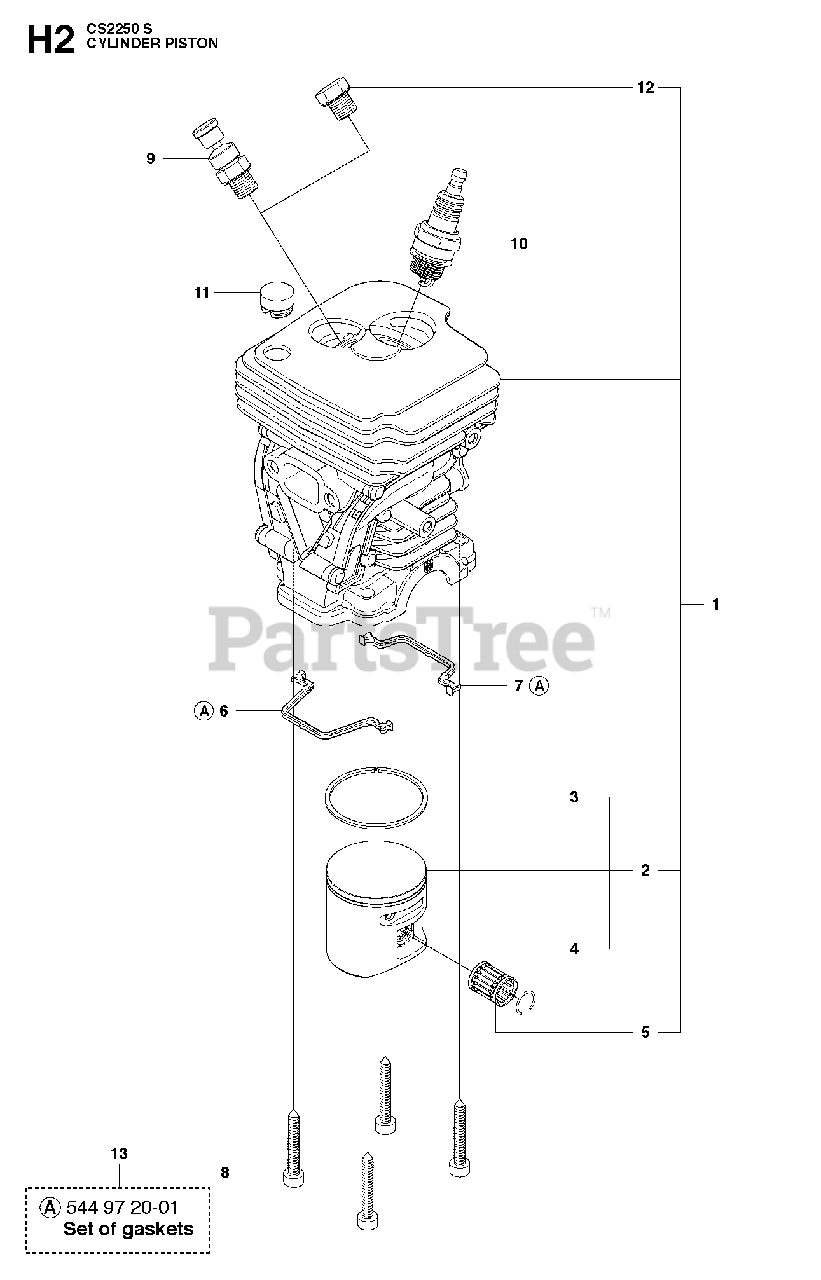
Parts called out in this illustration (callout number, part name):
2	PISTON ASSY
3	PISTON RING
4	CIRCLIP
5	NEEDLE BEARING
6	GASKET
7	GASKET
9	DECOMPRESSION VALVE
10	BPMR7A NGK SPARK PLUG
12	CYLINDER PLUG
13	GASKET KIT
